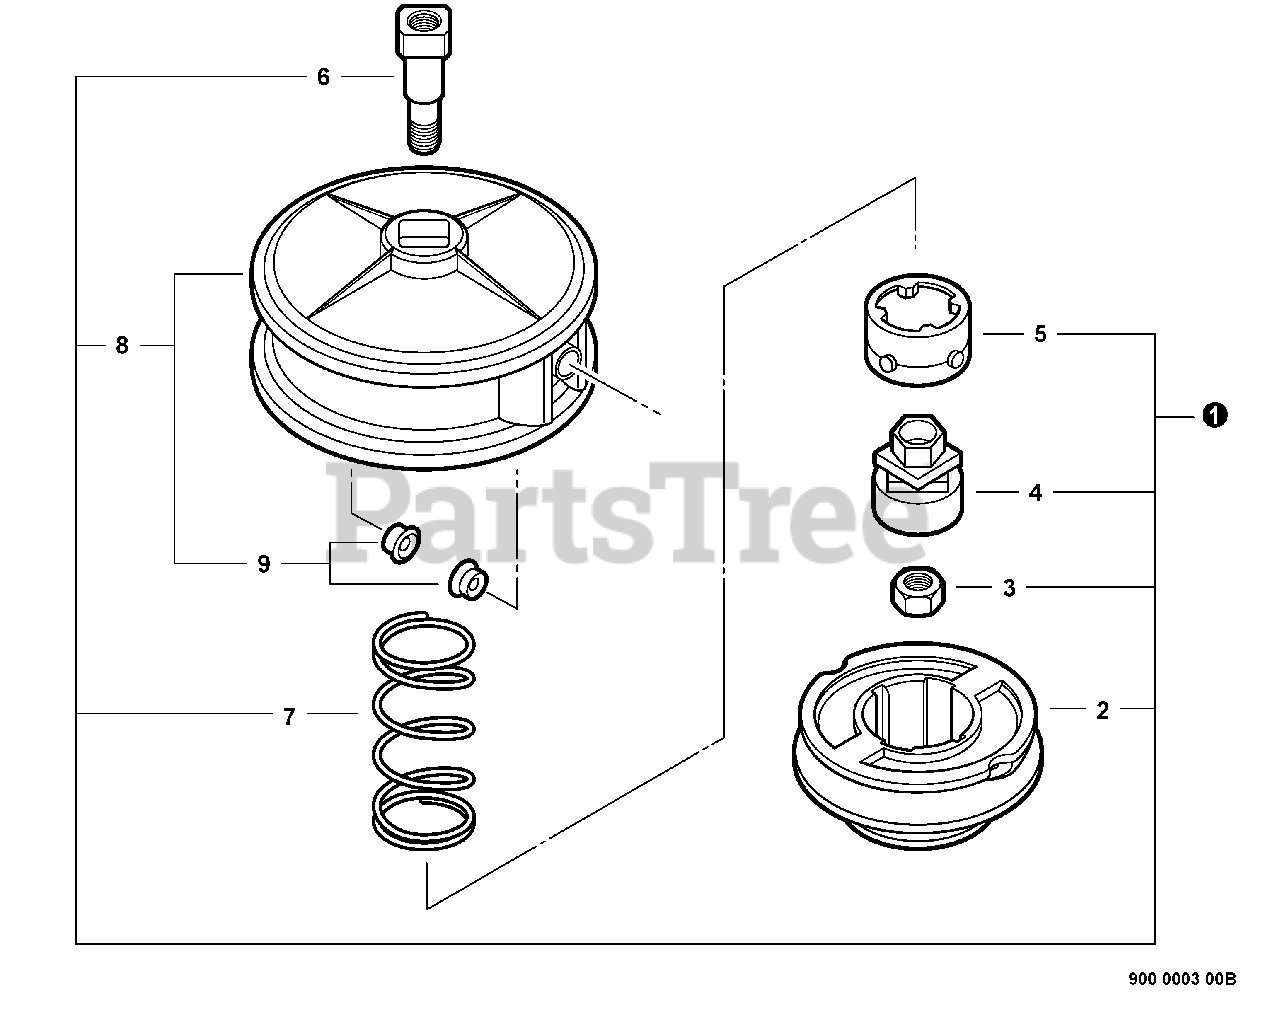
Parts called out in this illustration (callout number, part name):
1	TRIMMER HEAD, U-TURN
4	CAM, INNER
5	DRIVE, OUTER
6	STUD, ARBOR M10×1.25 LH
8	HOUSING ASSY, SPOOL
9	EYELET
